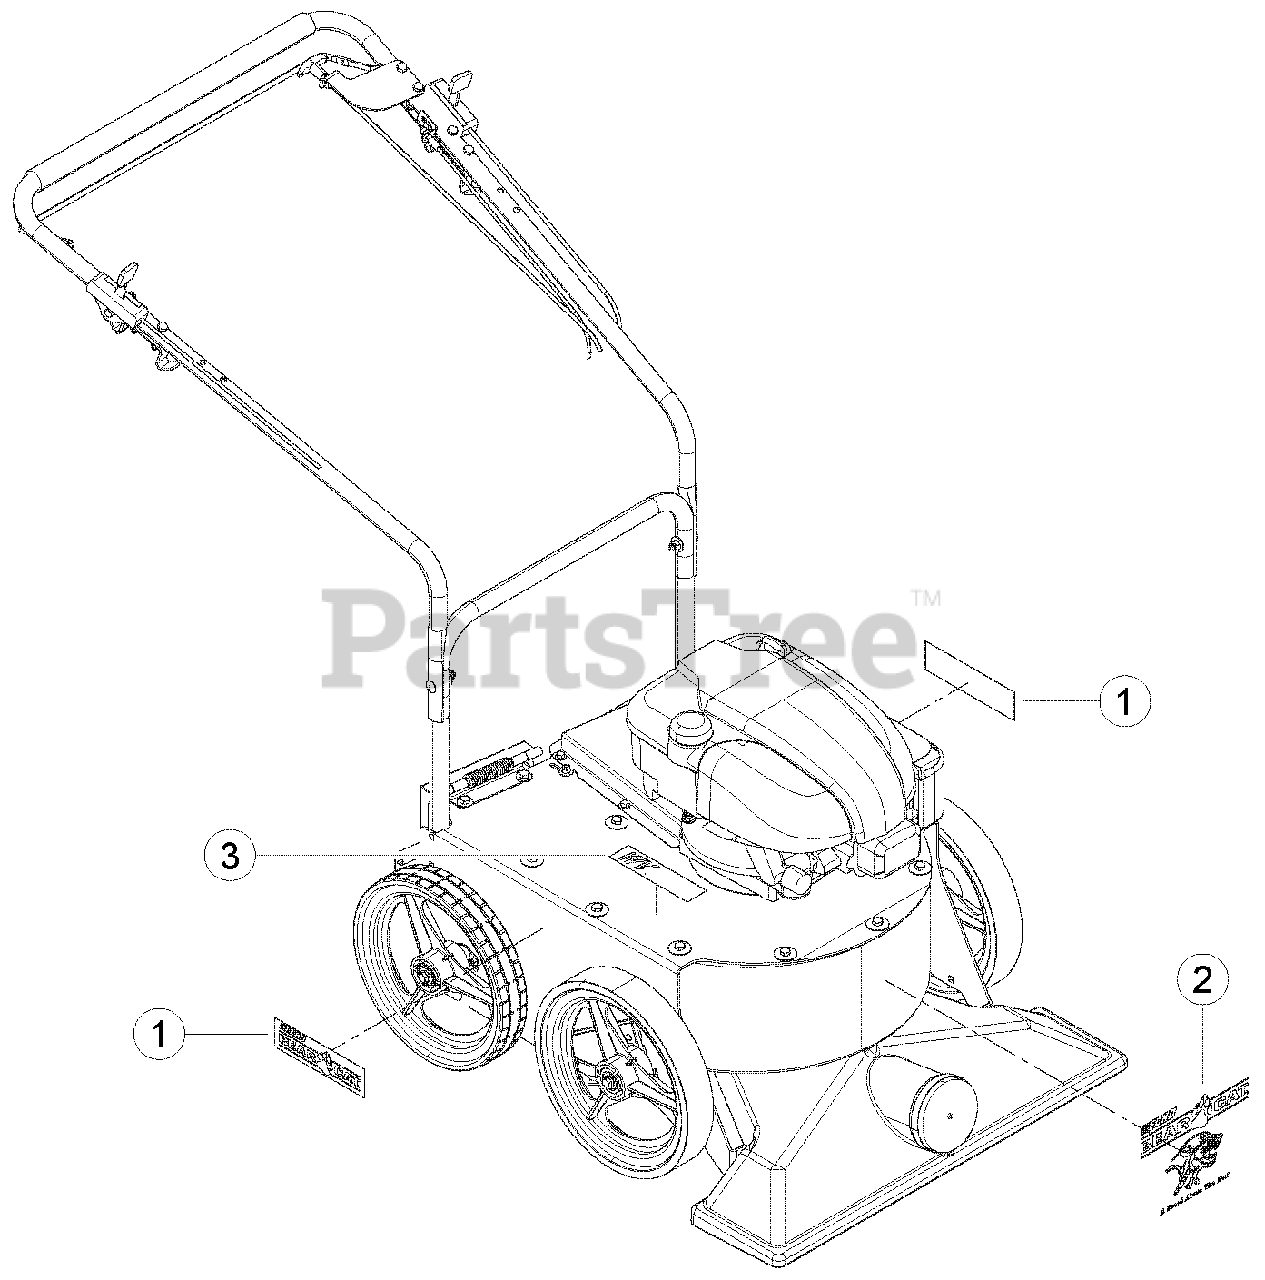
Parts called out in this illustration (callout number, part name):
1	DECAL, ECHO BEARCAT
2	DECAL, ECHO BEARCAT
3	DECAL, MODEL WV160
3	DECAL, MODEL WV160S
3	DECAL, MODEL WV190
3	DECAL, MODEL WV190S
